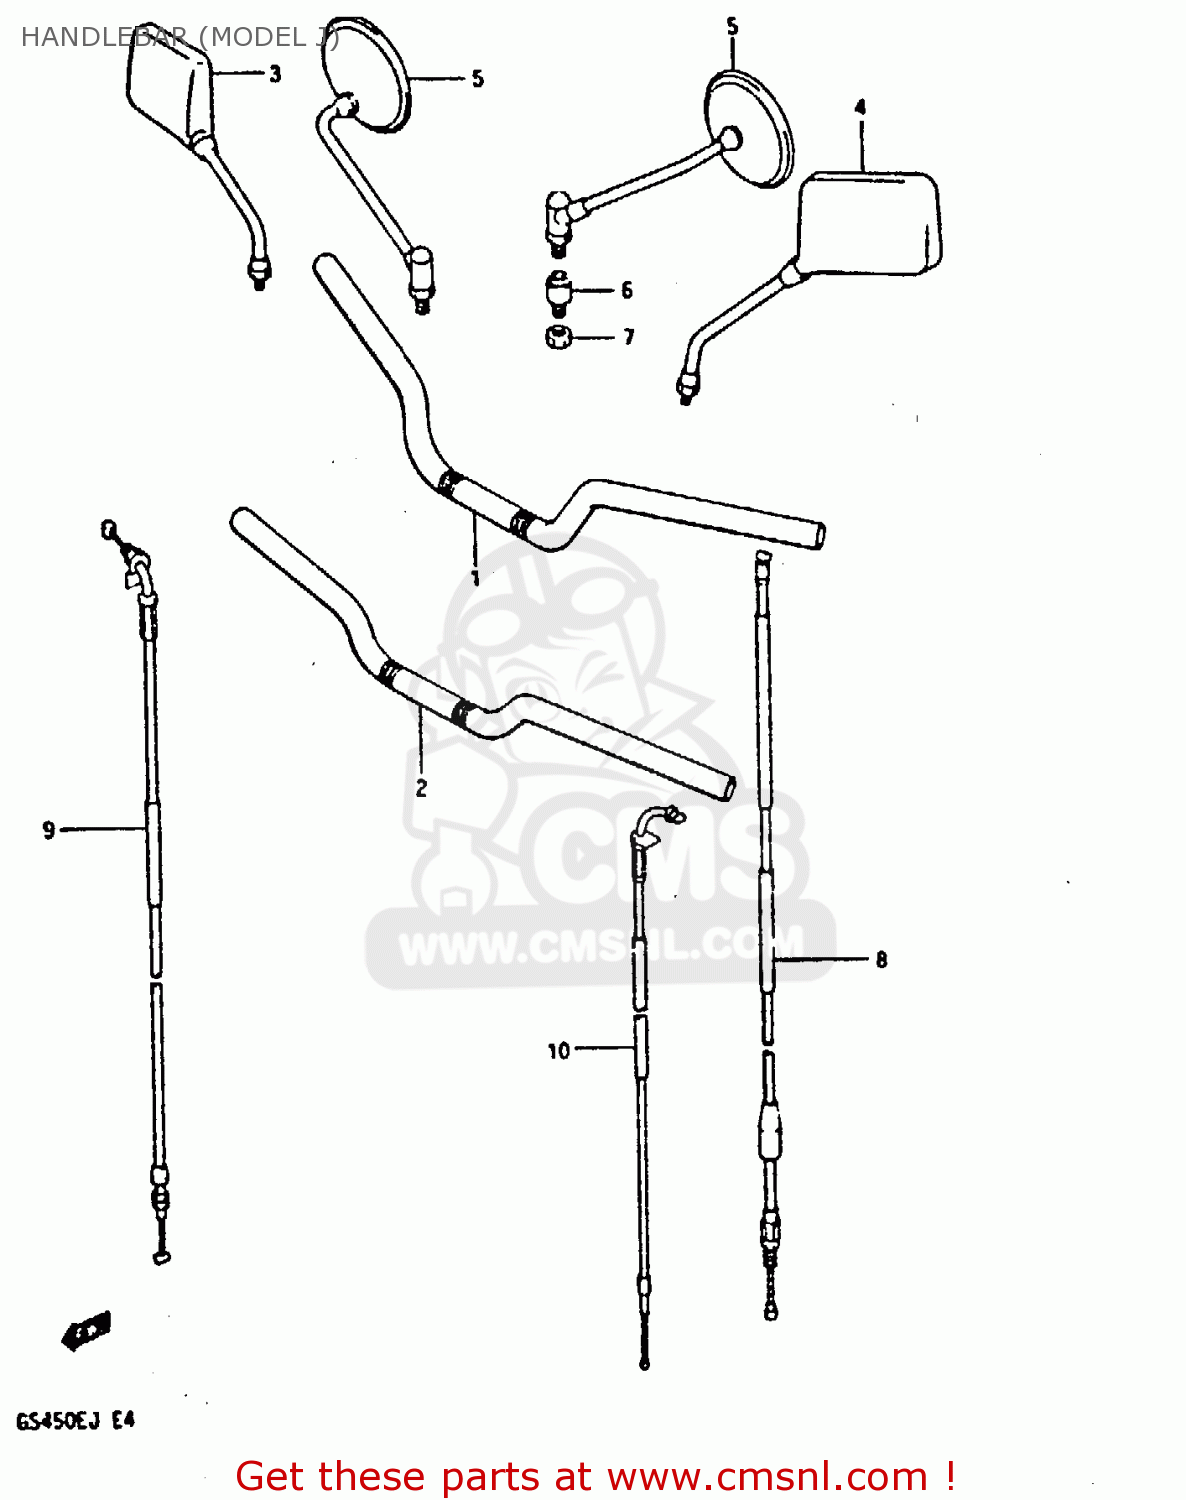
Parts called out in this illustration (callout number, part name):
1	HANDLEBAR
2	HANDLEBAR
3	MIRROR ASSEMBLY,REAR VIEW
4	MIRROR ASSEMBLY,REAR VIEW
5	MIRROR ASSY,RH
6	CUSHION,REAR VIEW MIRROR
7	NUT
8	CABLE ASSY,CLUTCH
9	CABLE ASSY,THROTTLE
10	CABLE ASSY,STA
